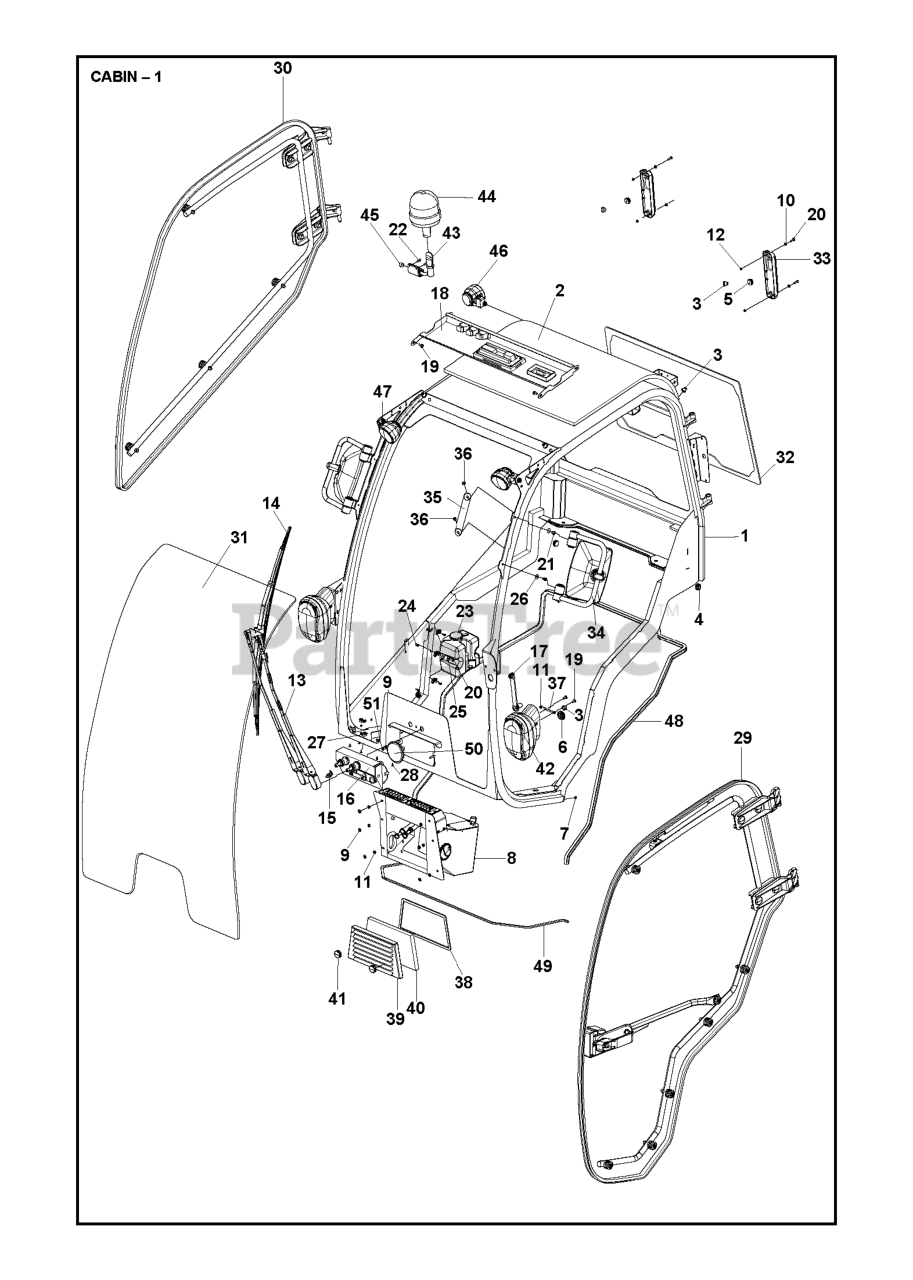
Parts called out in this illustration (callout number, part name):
11	LOCKNUT M6
12	LOCKNUT M5
51	LOCKNUT M6
